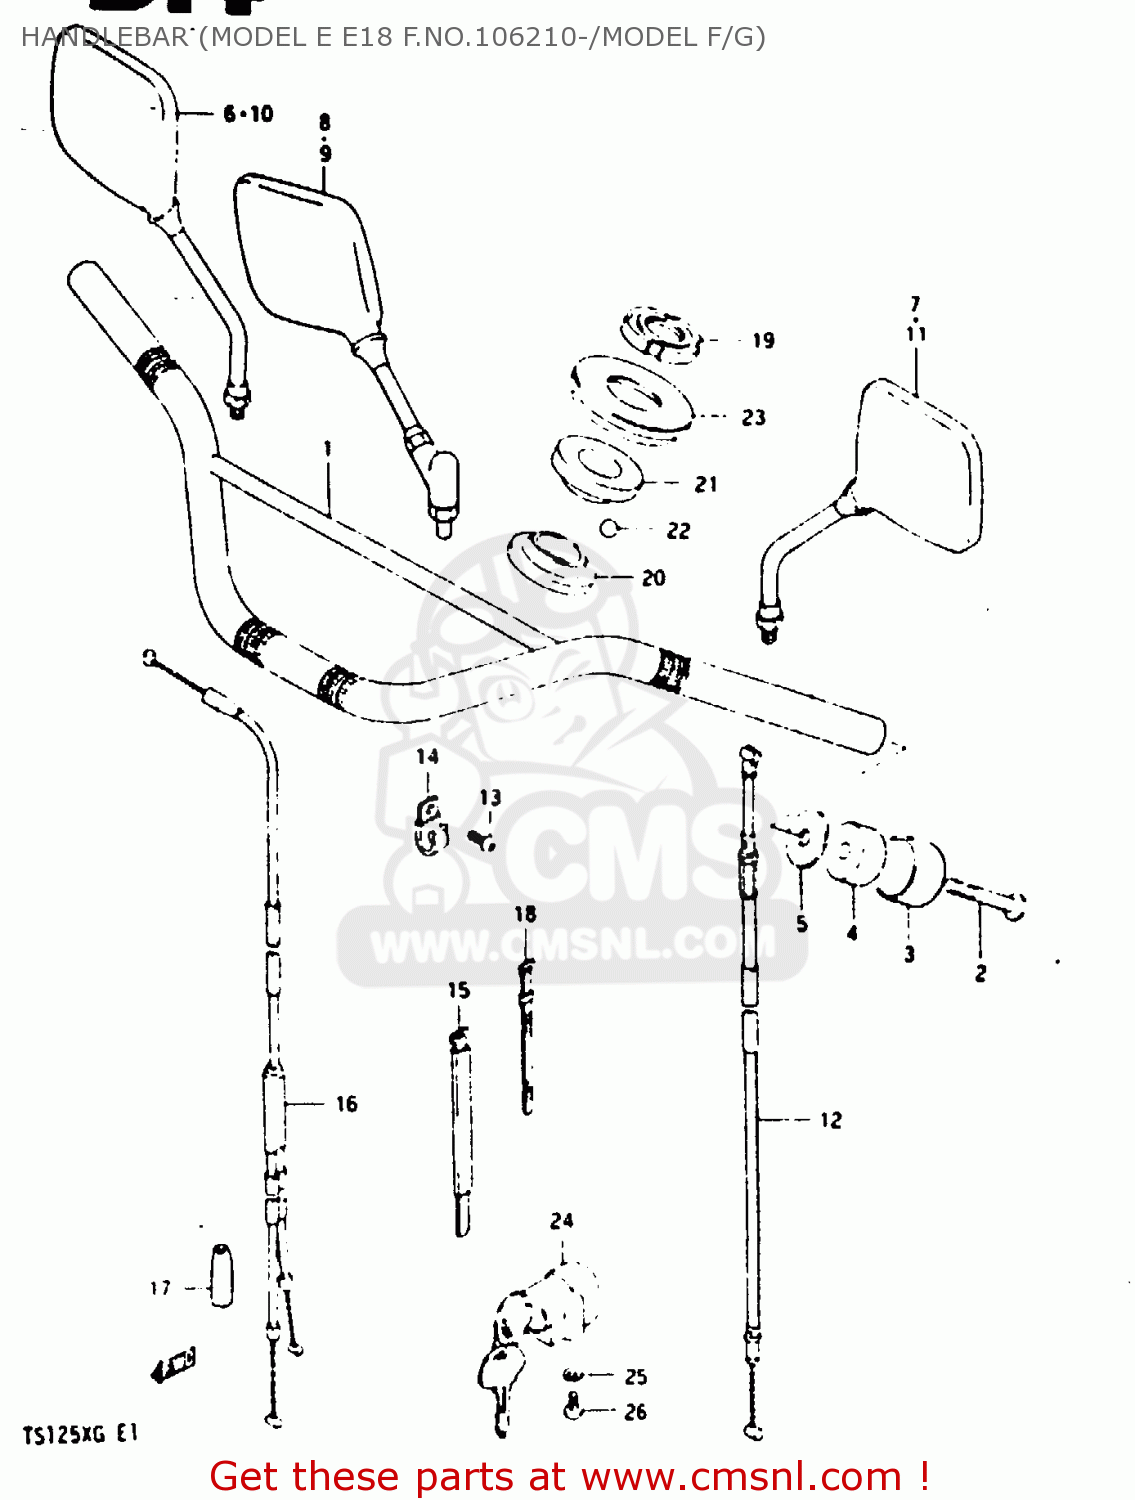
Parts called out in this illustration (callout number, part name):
1	HANDLEBAR (GOLD)
2	SCREW
3	CAP,HANDLE BALANCER
4	BALANCER,HANDLEBAR
5	SPACER,BALANCER
8	MIRROR ASSEMBLY,REAR VIEW
9	MIRROR ASSEMBLY,REAR VIEW
12	CABLE, CLUTCH
13	SCREW
14	CLAMP
15	CLAMP(L:250)
16	CABLE ASSY, THROTTLE
17	SEAL,DUST(7X18X30)
18	CLAMP
19	NUT,STEERING STEM
20	RACE,STEERING,INNER,UPPER
21	RACE,STEERING,OUTER,UPPER
22	BALL
23	SEAL,STEERING UPR DUST
24	LOCK ASSY,STEERING
25	LOCK WASHER
26	SCREW
